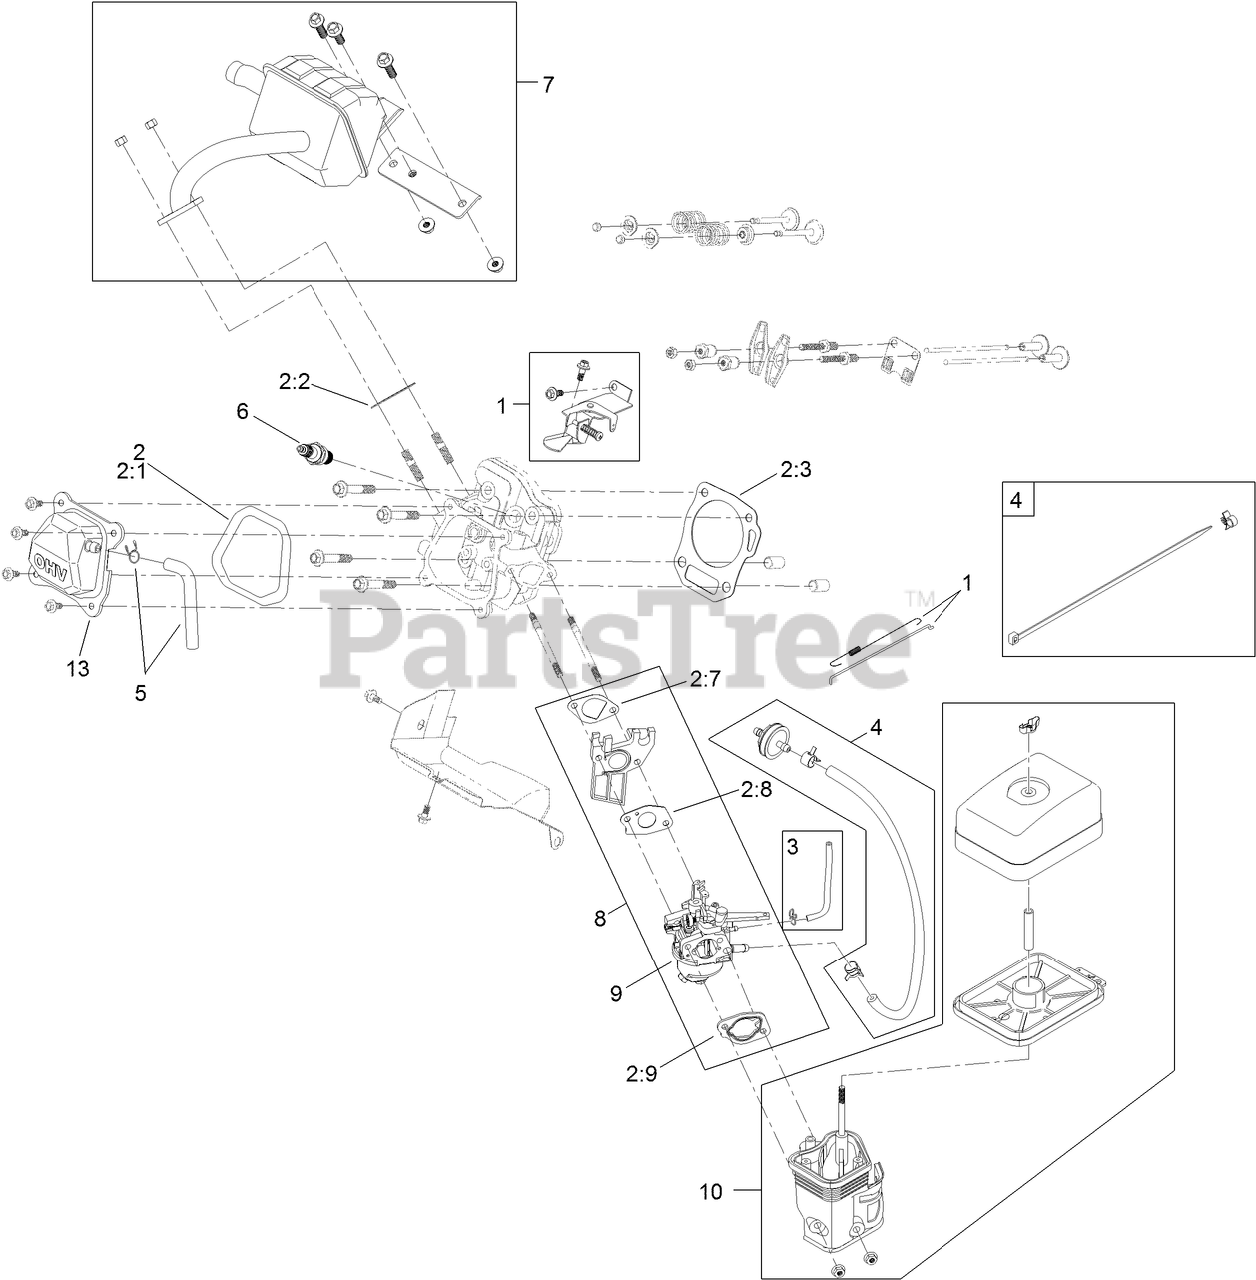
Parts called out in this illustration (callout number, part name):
1	GOVERNOR KIT
2	GASKET AND SEAL KIT
2:1	GASKET-COVER, VALVE
2:2	Gasket-Exhaust
2:3	GASKET-HEAD, CYLINDER
2:4	Loose Parts Package
2:5	Loose Parts Package
2:6	GASKET-COVER, CRANKCASE
2:7	GASKET-CARBURETOR
2:8	GASKET-CARBURETOR
2:9	GASKET-CARBURETOR
4	FUEL LINE KIT
5	BREATHER TUBE KIT
7	MUFFLER KIT
8	CARBURETOR KIT
9	CARB REPAIR KIT WITH GASKETS
10	HEATER BOX KIT
13	VALVE COVER ASM
